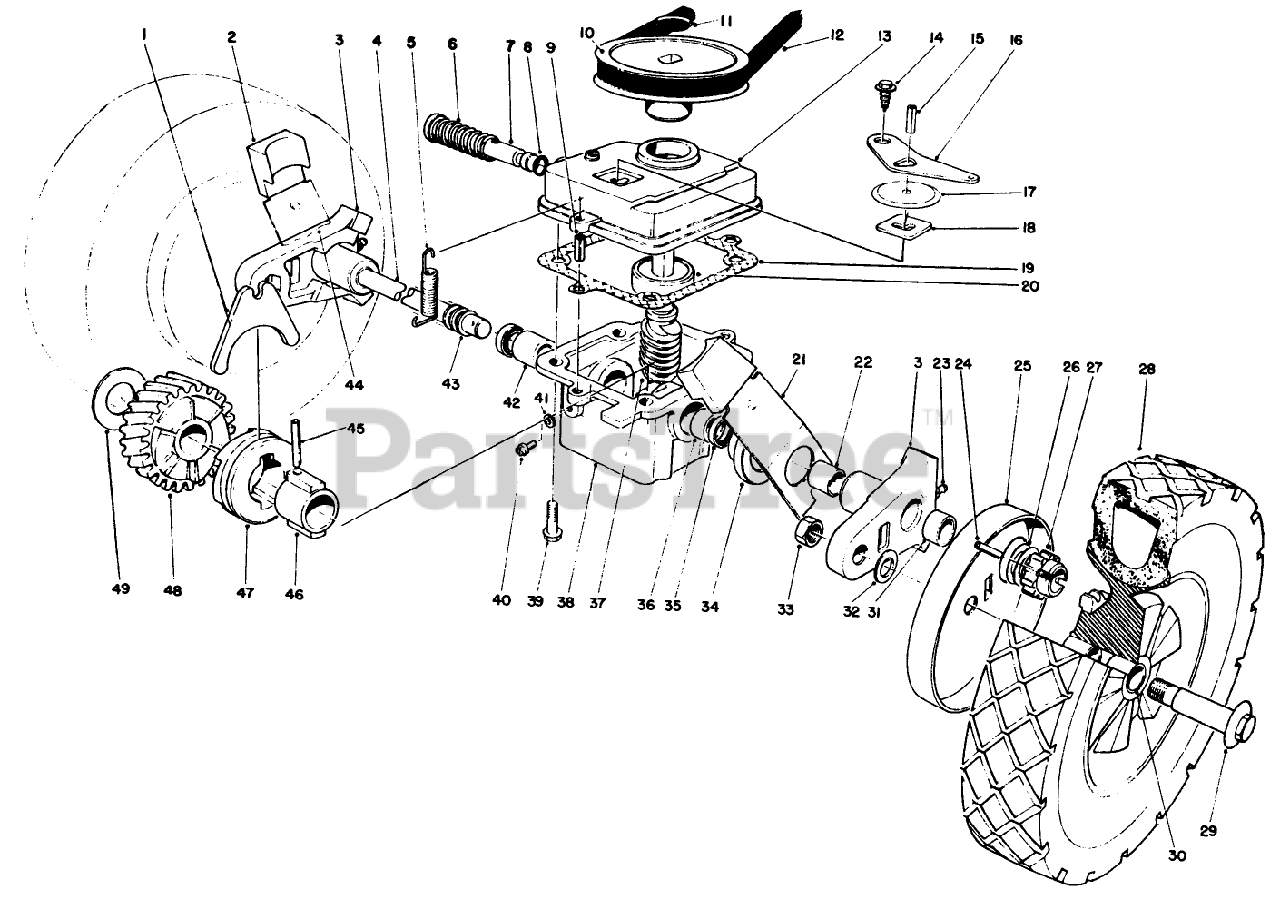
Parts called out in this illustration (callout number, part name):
1	SHIFTER FORK
2	KNOB-ARM
3	PIVOT ARM ASM
4	DRIVE SHAFT (SERVCE)
5	TENSION SPRING
6	SPRING
7	SHIFTER ROD
8	O-RING
9	3/16 X 1/2 ROLL PIN
10	PULLEY
11	PUSH-ON 93-3236
12	BELT-V
15	PIN-ROLL
16	SHIFTER ARM
17	TRANS DUST COVER
18	LATCH PLATE
19	GASKET
20	BEARING - BALL
22	BUSHING
23	FITTING-GREASE
25	WHEEL COVER
27	PINION GEAR 14T
28	WHEEL-TIRE ASM SERVICE
29	WHEEL BOLT
30	BUSHING
31	BUSHING
32	WASHER
33	NUT-LOCK
34	CAP-END
35	SEAL-OIL
36	BUSHING
37	WORM SHAFT & GEAR SET
38	GEAR CASE ASM
40	NYLON SCREW
41	FILL PLUG GASKET
42	BUSHING
43	COVER-SHAFT, DRIVE
44	Spring Arm Assembly R.H.
45	COIL PIN
46	SLEEVE
47	CLUTCH JAW
48	Helical Gear
49	THRUST WASHER
